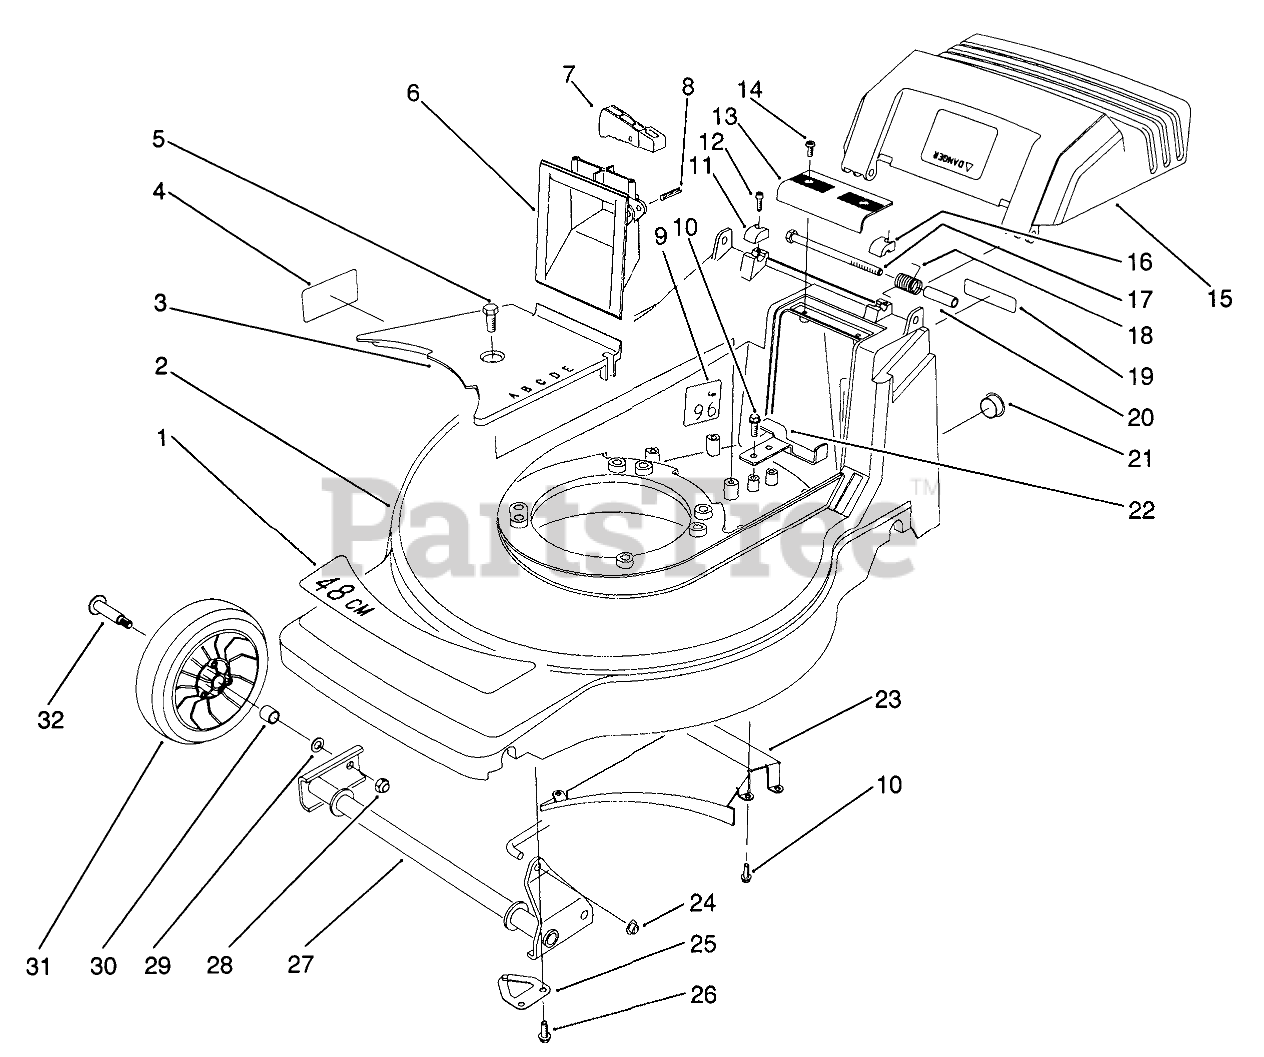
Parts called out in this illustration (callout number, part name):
1	DECAL - DECK
2	Housing-48cm
3	BELT COVER
4	Decal Danger
5	SCREW-HWHTF
6	GRIP - LOWER
7	TRIGGER - HOC
8	PIN-SPIRAL
9	Decal-Noise
10	SCREW-HWHTF
11	CAP-HINGE BOLT, RH
12	SCREW-HSH
13	GRIP-UPPER
14	SCREW-PPH, PLASTITE
15	Door-Discharge
16	CAP-HINGE BOLT, LH
17	SCREW-HH
18	DOOR SPRING
19	DECAL FRENCH REGUL.
20	SPACER-DOOR
21	DOME PLUG (DP-1000)
22	REAR BELT GUIDE
23	Ramp-Discharge
24	NUT-PUSH
25	SHAFT RETAINER ASM
26	Screw
27	FRONT PIVOT WA
28	Nut
29	WASHER
30	BUSHING
31	Wheel & Tire Assembly (Incl. Ref. #30)
32	BOLT-WHEEL
